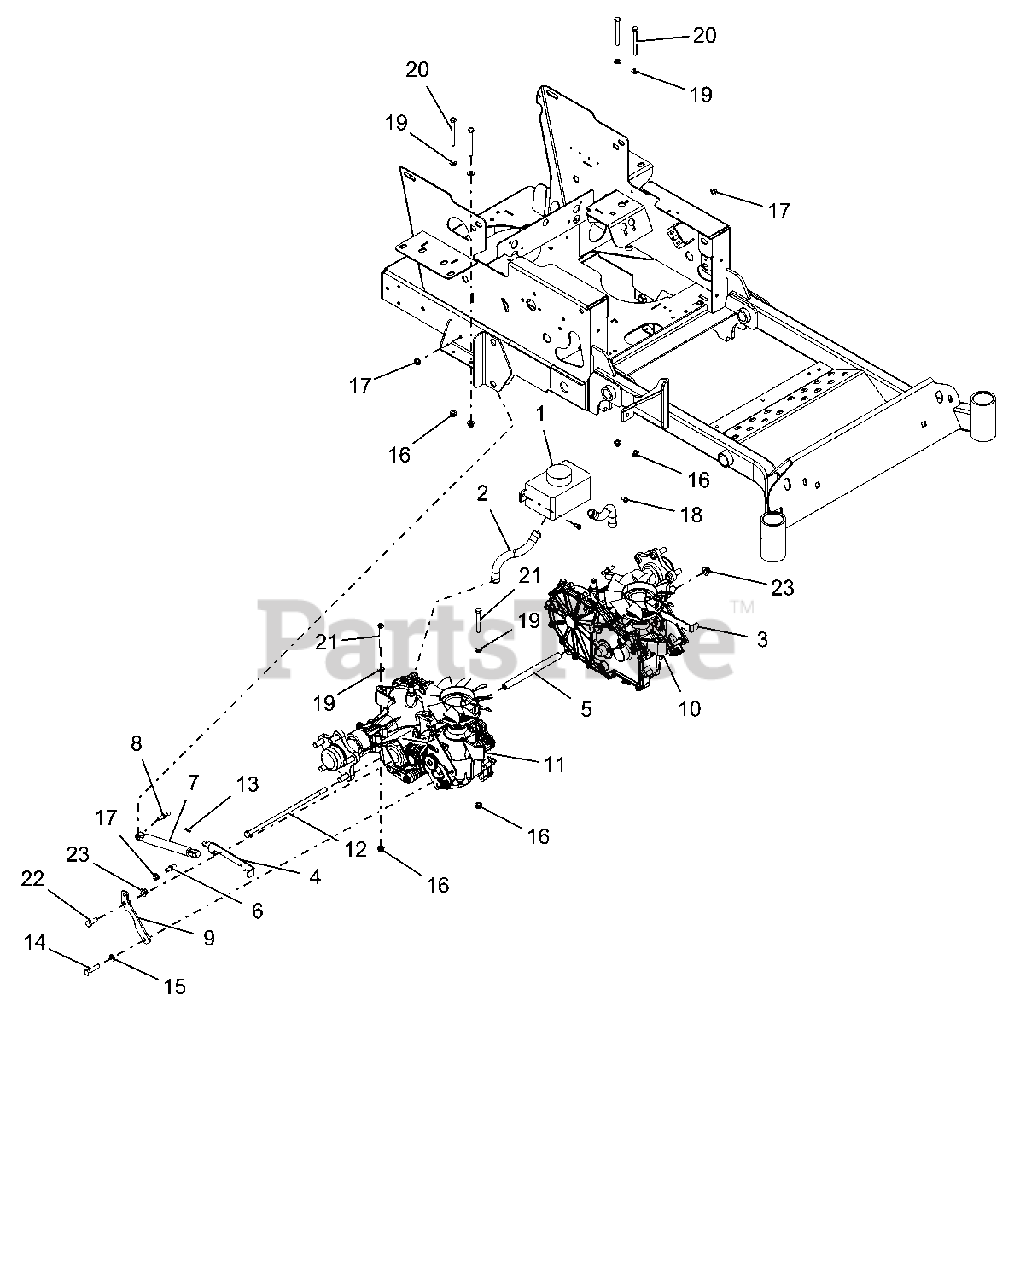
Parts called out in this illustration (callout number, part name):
1	TANK, EXPANSION
2	ASM, HYDRO OVERFLOW TANK HOSE
3	RH DUMP VALVE LEVER - BLACK
4	LH DUMP VALVE LEVER - BLACK
5	SPCR,.406 ID X .630 OD X 7.724
6	STUD- BALL
7	DAMPER
8	STUD-BALL-THREADED
9	TRANSMISSION DAMPER MTG PLT-BL
10	TRANSAXLE, ZT3100, LH
11	TRANSAXLE, ZT3100, RH
12	BLT HEX, .38-16X11.00 GR5 YWZC
13	PIN-HAIR INT .06X.18X.77
14	@BLT-HEX .38-16X1.50 GR5 YWZC
15	@WSHR-LK .38X.094 REG YWZC
16	@NUT-LK-NYL-FLG .31-18 YWZC
17	@NUT-LK-TOP-FLG .31-18 YWZC
18	SCR-TAP .25-20X.50 HWH TR YWZ
19	@WSHR-FL-STL.344X.688X.065YWZC
20	@BLT-HEX .31-18X3.00 GR5 YWZC
21	@BLT-HEX .31-18X2.50 GR5 YWZC
22	@BLT-HEX .38-16X1.00 GR5 YWZC
23	@NUT-LK-NYL-FLG .38-16 YWZC
